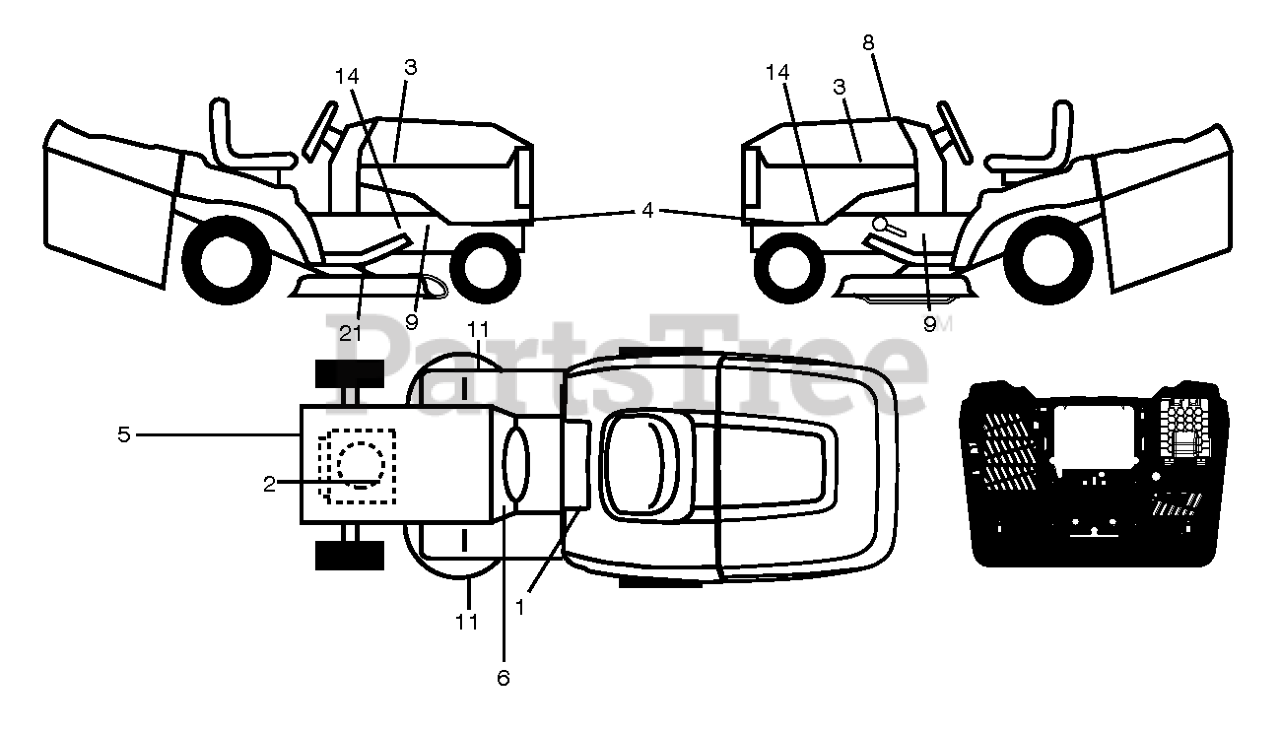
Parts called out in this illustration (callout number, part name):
1	DECAL.WARNING.COMBINED.T/CRD
2	DECAL.ENGINE.WARNING
3	DECAL.WB.178MM.15.HUSQ.NEWBRAN
4	DECAL TRACTOR SIDE PANEL DECAL
5	DECAL.ENG.BS.344CC.HS.382271
6	DECAL.SNOWFLAKE.MS498.HUSQ
9	DECAL.WARNING.SERVCE/FIRE
11	DECAL.CUTFINGER.CE.02
14	DECAL.CHASSIS.HOT.MUFFLER
21	DECAL BELT ROUTING DECAL DECAL
